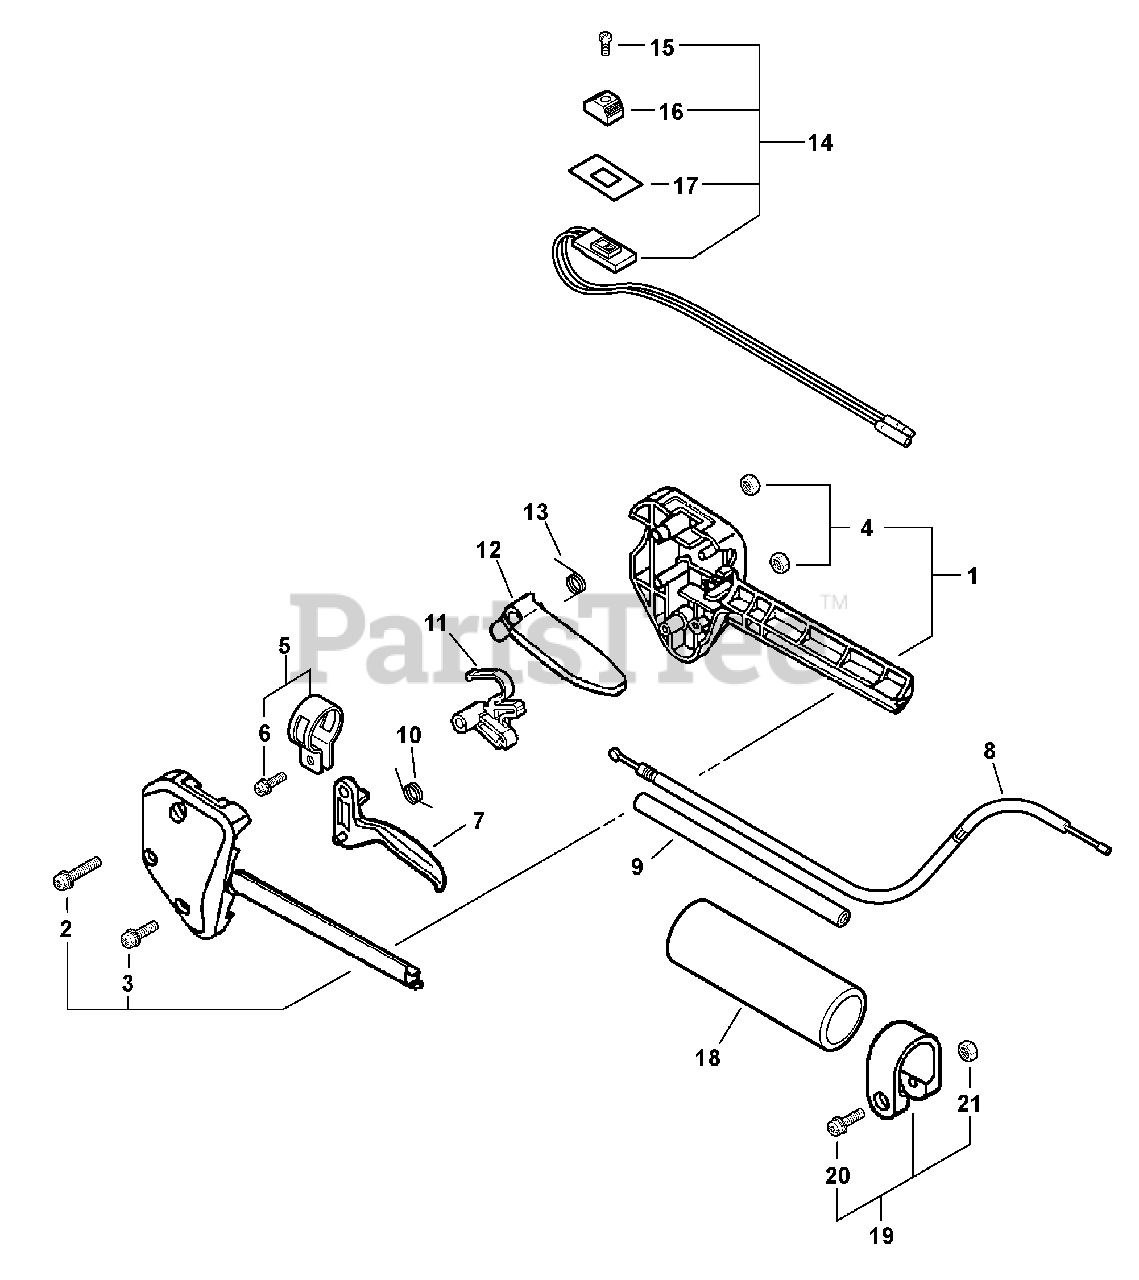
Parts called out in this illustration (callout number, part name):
1	HANDLE KIT, CONTROL
2	SCREW 5×35
3	SCREW 5×25
4	NUT M5
5	CLAMP KIT
6	SCREW 5×14
7	TRIGGER, THROTTLE
8	CABLE, THROTTLE
10	SPRING, TORSION
11	LOCKOUT, THROTTLE
12	LOCKOUT, THROTTLE
13	SPRING, TORSION
14	SWITCH ASSY, ON-OFF
15	SCREW 3×10
16	KNOB, SWITCH - ORANGE
17	LABEL, SWITCH
18	GRIP, HANDLE
19	CLAMP KIT
20	SCREW 5×28
21	NUT M5
